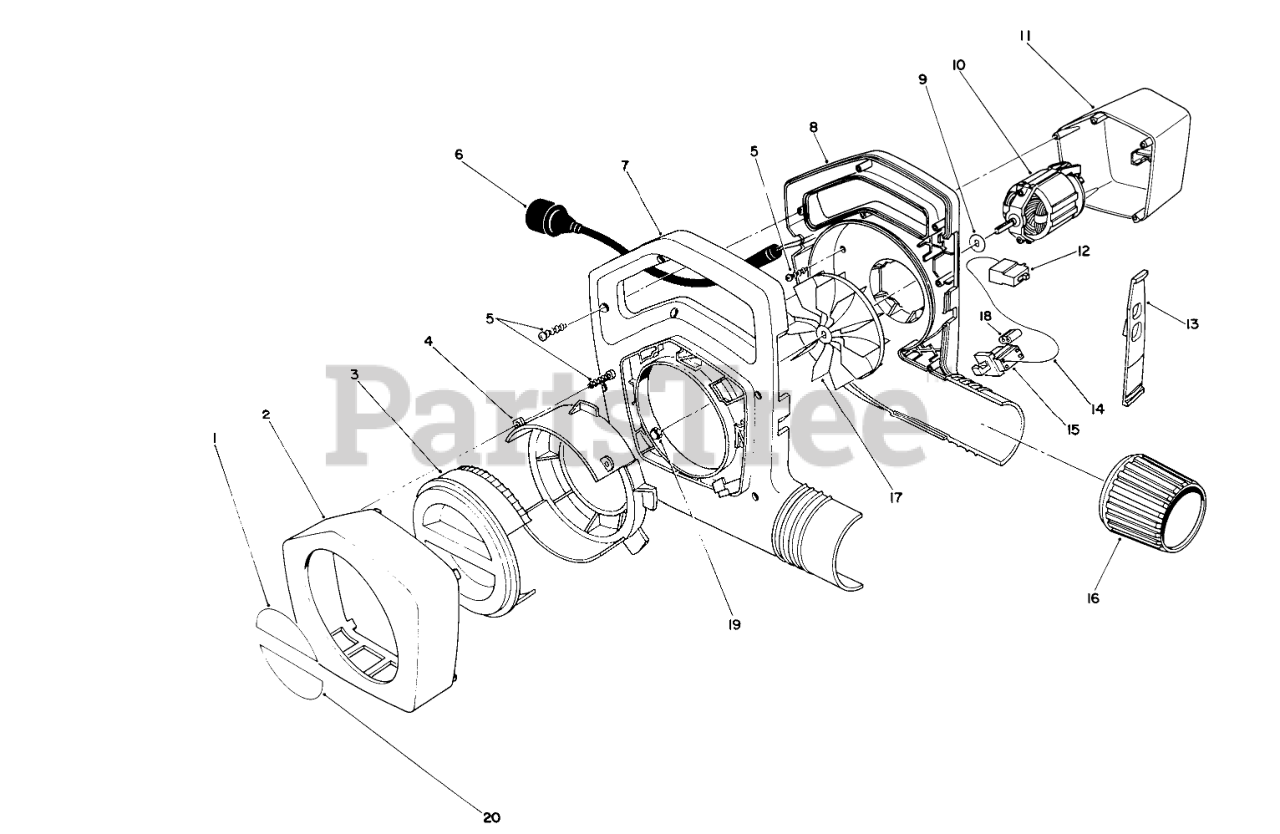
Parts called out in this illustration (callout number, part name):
1	UPPER CHOKE DECAL-CLUB
2	Ring-Trim
3	Adjuster-Choke
4	Ring-Tab
5	Screw
6	Cord-Power Supply
7	BLOWER HOUSING, RH
8	Housing-L.H.
9	Washer-Impeller
10	Motor
10	MOTOR, BLOWER (450/550)
11	HOT STAMPED MOTOR COVER
11	Cover-Motor
12	Switch-On/Off
13	Cam-Switch-On/Off
14	WIRE -INTERNAL
15	SWITCH-INTERLOCK
16	Collar-Output
17	Impeller
17	IMPELLER-NEW STYLE
18	NEW STYLE DUST PLUG
19	NUT-LOCK, CAP
20	LOWER CHOKE DECAL-CLUB
